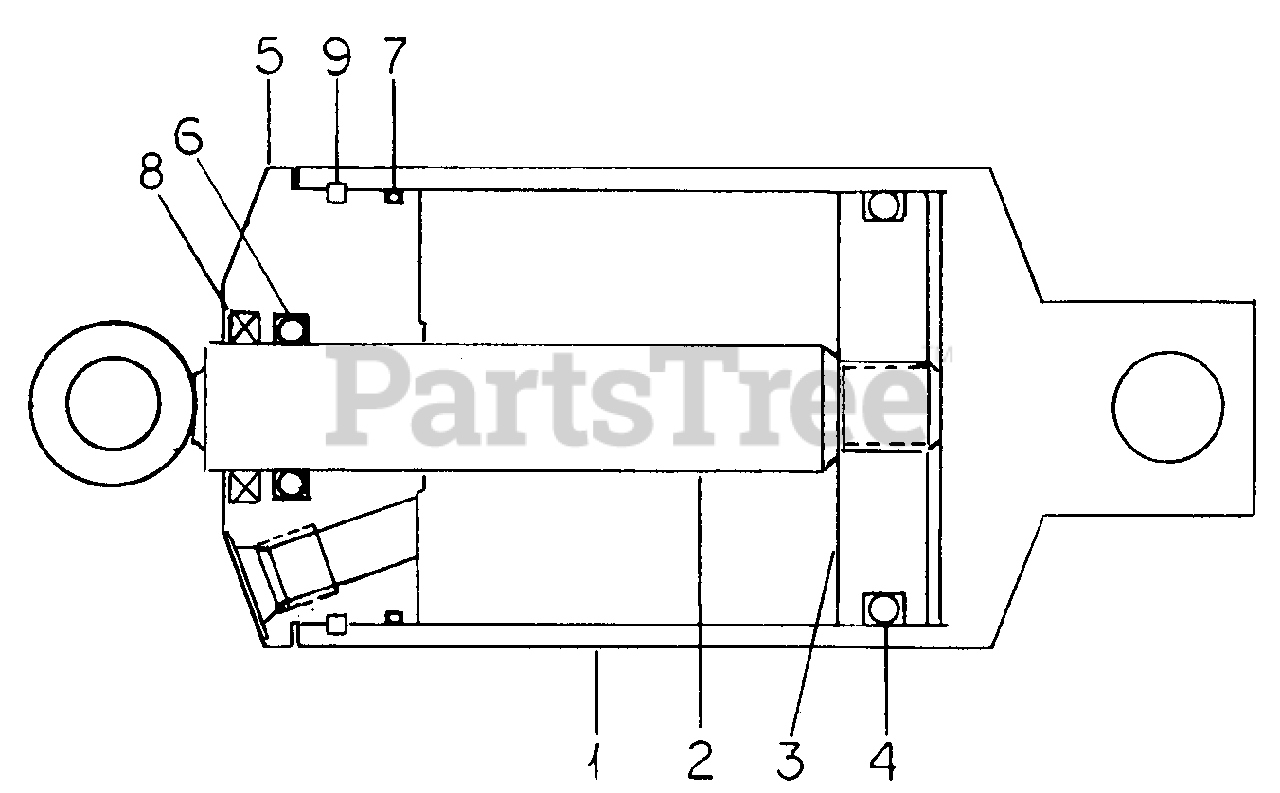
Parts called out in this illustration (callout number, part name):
1	Body Assy, Hyd Cyl
2	Rod Assy, Hydraulic Cylinder Piston
3	Piston, Hyd Cylinder
4	O-Ring, 2-1/8 X 2-1/2 X 3/16 Hyd Cyl Piston
5	Head, Hyd Cyl Front
6	O-Ring, 3/4 X 1 X 1/8 Hyd Cyl Piston Rod
7	O-Ring, 2-5/16 X 2-1/2 X 3/32 Hyd Cyl Front Head
8	Seal, Hyd Cyl Piston Rod Wiper
9	Retainer, Hyd Cyl Front Head
